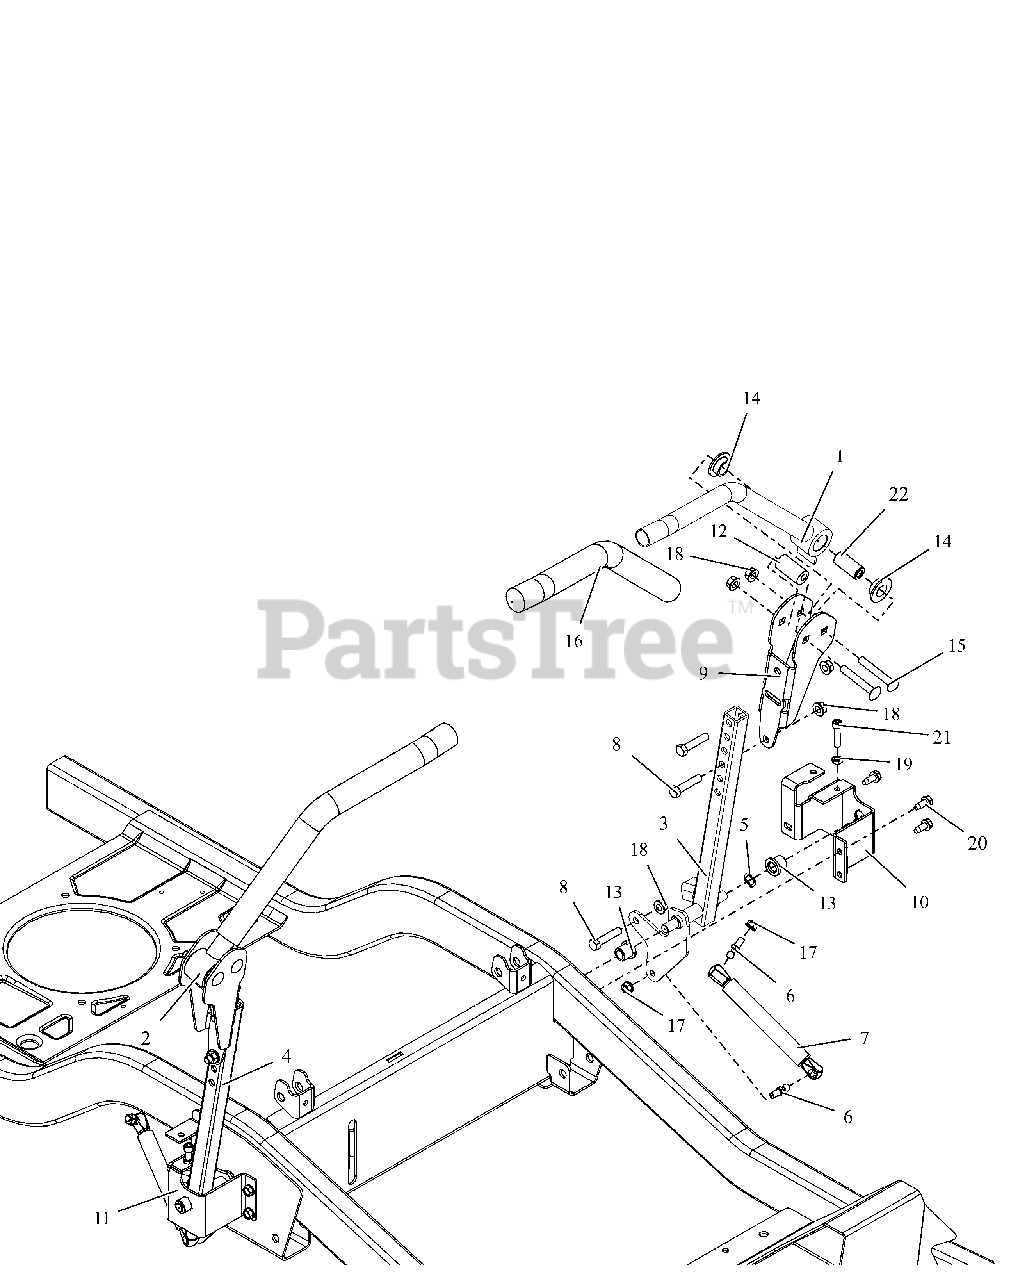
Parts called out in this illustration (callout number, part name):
1	WLDMT, CONTROL HANDLE- BLK
2	WLDMT, CONTROL HANDLE- BLK
3	WLDMT, STEERING LH
4	WLDMT, STEERING RH
5	WAVE WASHER .531X.781X.125FH
6	STUD- BALL
7	DAMPER
8	BLT, HEX .38-16X1.75 G5 ZCC
9	ADJ UPPER CONTROL ARM BRKT-BLK
10	BRKT, STEERING ARM MOUNT -LH
11	BRKT, STEERING ARM MOUNT -RH
12	BSHG, ECCENTRIC.406X.875X1.625
13	BHSG-FLG .500X.750X.750X.125
14	BSHG-FLG .762X1.48X.44 NYL
15	BLT, RHSSN.38-16X2.50 G5 ZCC
16	GRIP, HANDLEBAR
17	NUT,LK-CTR-FLG .31-18 GF ZCC
18	NUT-LK-TOP-FLG .38-16 ZC120
19	NUT-JAM .312-18 G2 ZCC
20	SCR,TAP .312-18X.75 HWH TR ZCC
21	SCR, SKH .312-18X1.25 GR8 ZC120
22	SPACER, STEERING ARM
